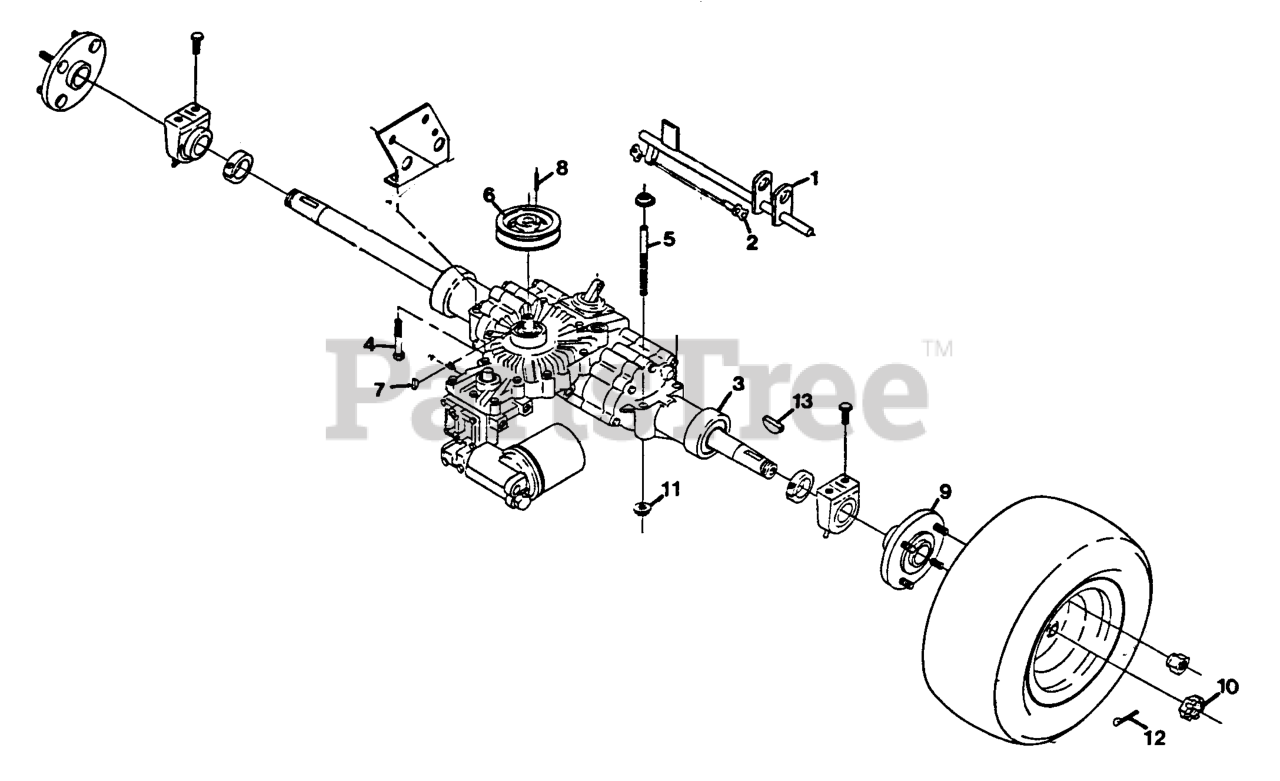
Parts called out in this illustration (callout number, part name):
1	Jackshaft Wldmt - Brk
2	LINK,CONNECTING
5	PIN,GUIDE
12	PIN-COTTER
